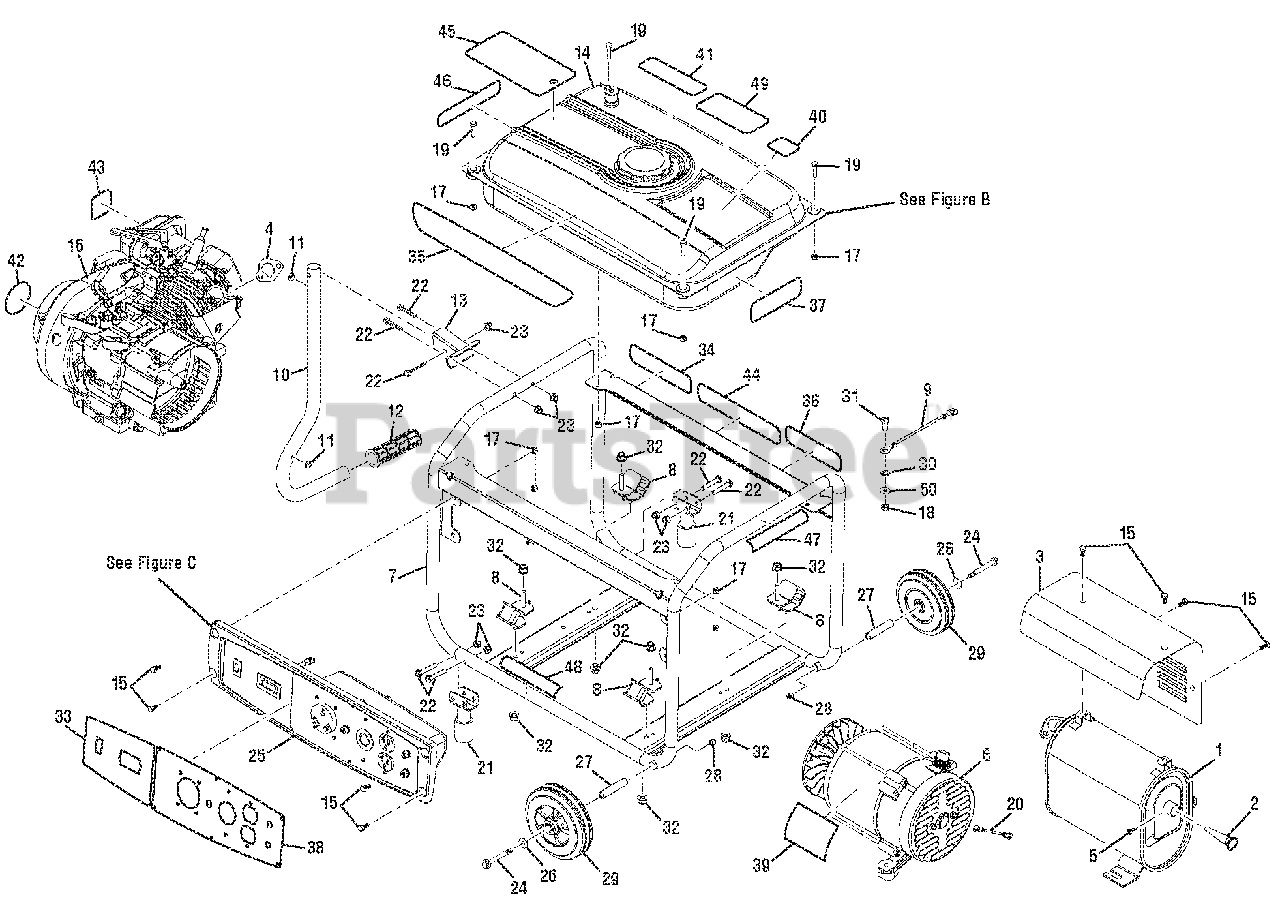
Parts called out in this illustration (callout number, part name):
2	Spark Screen
3	Heat Shield
4	Exhaust Gasket
5	Set Screw (Spark Arrestor)
6	Generator Head Assembly
7	Carrier Assembly
8	Isolators (45deg)
9	Ground Wire Assembly
10	Handle Assembly
11	Handle Bumper
12	Handle Grip
13	Handle Bracket
14	Fuel Tank Assembly
15	Screw (M6 x 14 mm)
16	Engine (RATO R210)
17	Lock Nut (M6)
18	Lock Nut (5/16-18)
19	Bolt (M6 x 20 mm, Hex Hd.)
20	Bonding Wire
21	Foot Assembly
22	Bolt (1/4-20 x 1.5 in.)
23	Lock Nut (1/4-20)
24	Bolt (3/8-16 x 4.25 in.)
25	Panel Assembly
26	Washer (3/8 in.)
28	Lock Nut (3/8-16)
29	Wheel (7 in.)
30	Star Washer (5/16 in.)
31	Bolt (5/16-18 x 19 mm)
32	Flange Nut (M8)
33	Control Panel Label (Left)
34	Black Max Label
35	Logo Label
36	Hot Surface Label
37	Combustion Label (Eng/Sp)
38	Control Panel Label (Right)
39	Data Label
40	E85 Label
41	CPSC Label
42	Recoil Housing Label
43	Choke Label
44	Ground Warning Label
45	Danger Hang Tag
46	Engine Start Label
47	Fire Danger Label
48	Lubricant Label
49	Warning Label
50	Lock Washer (5/16 in.)
